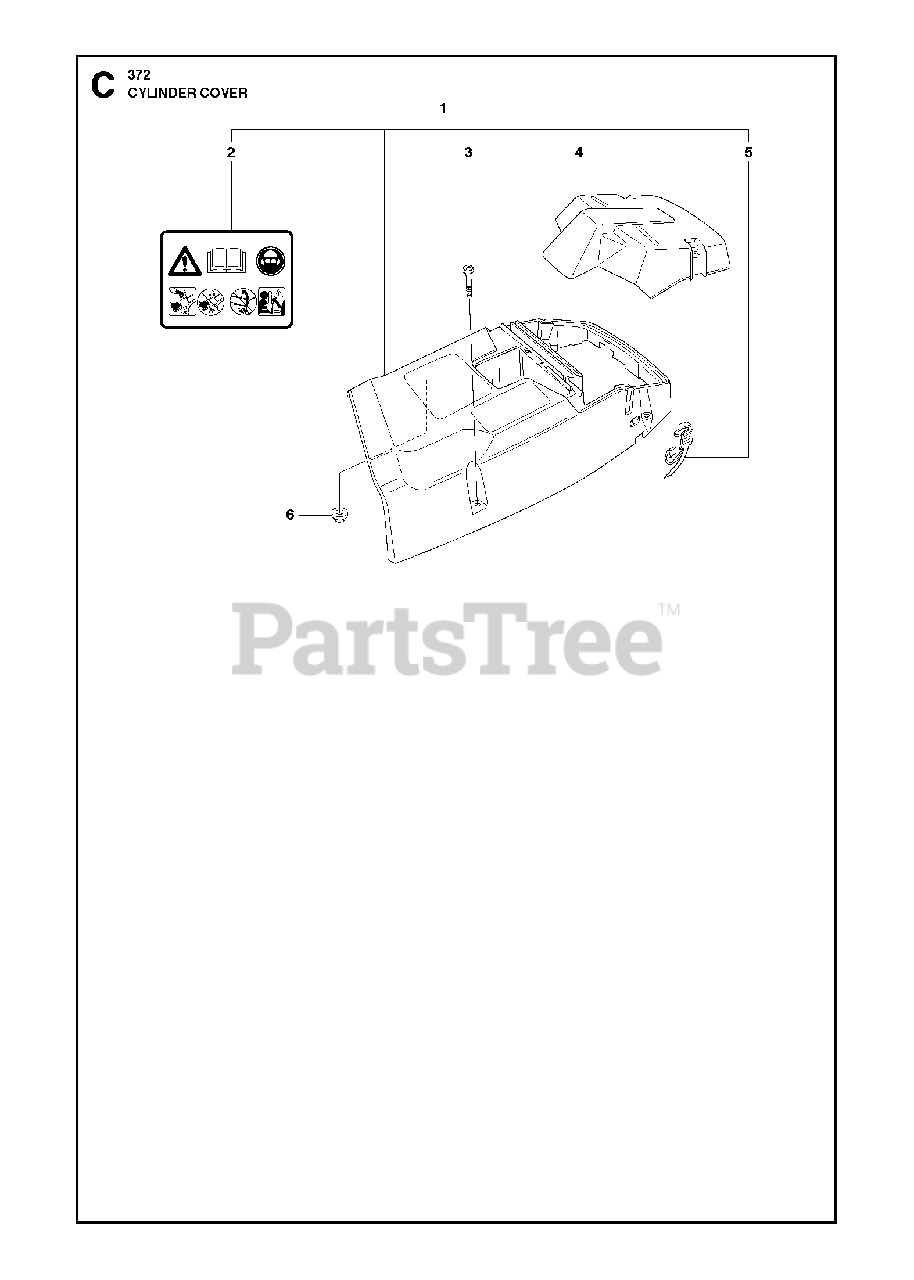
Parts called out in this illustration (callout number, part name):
1	TOP COVER
2	DECAL
3	SCREW
4	COVER
5	HOLDER
